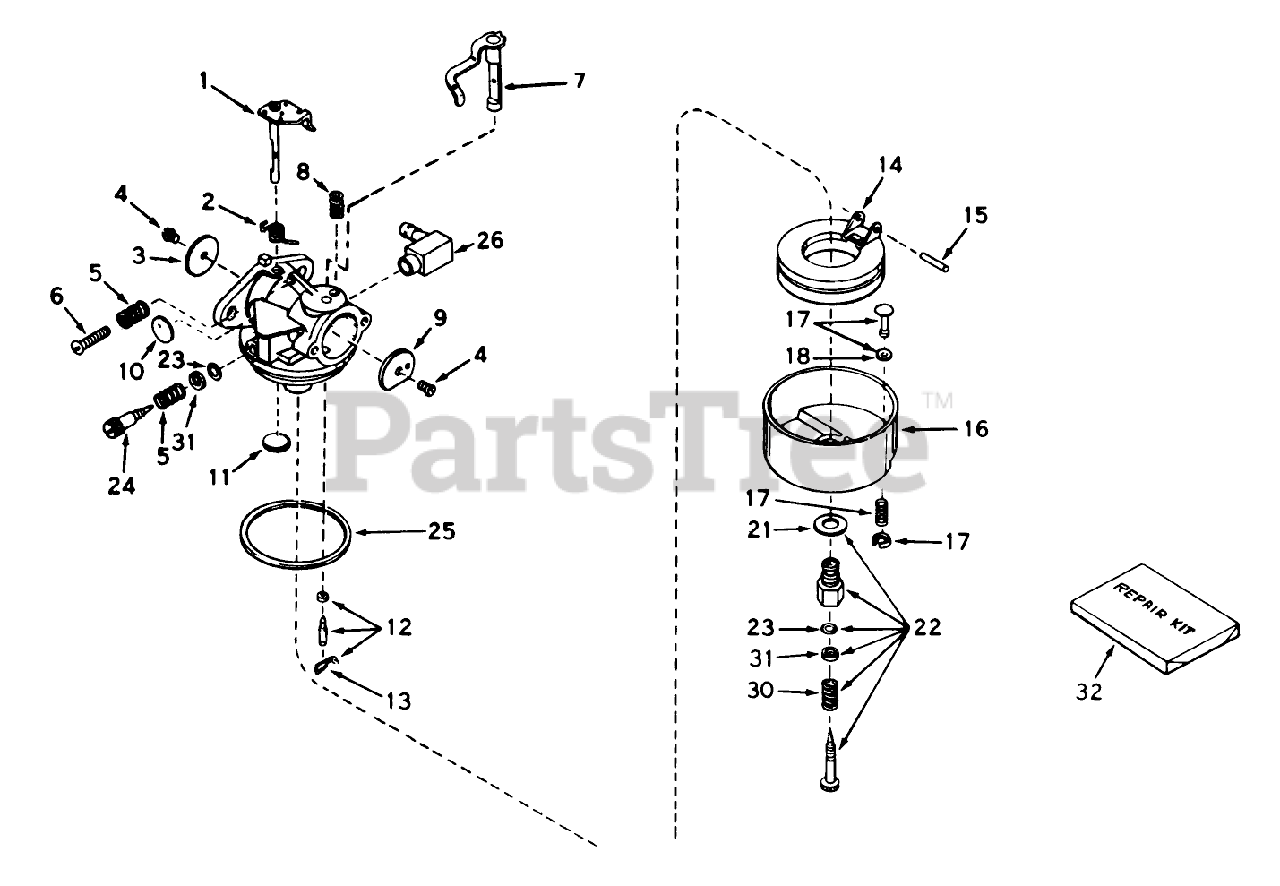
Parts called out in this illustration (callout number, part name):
1	Throttle Shaft and Lever ASM
2	Spring, Throtte Return
3	Shutter-Throttle
4	Screw-Shutter
5	Spring-Tension
6	Screw-Throttle Crack Screw / Idle Speed
7	Shaft/Lever Assy., Choke
8	Spring-Positioning, Choke
10	Plug-Welch, Idle Mixture Well
11	Plug-Welch, Atmospheric Vent
12	Inlet Needle, Seat Clip Assy. (Incl. No. 13)
13	Clip-Spring
14	Float,Carburetor
15	Shaft-Float
16	Bowl-Float (no drain)
17	Bowl Drain ASM
18	Gasket-Plunger, Drain
21	Washer-Bowl Nut
22	Adjustment Screw Assy., Main (Incl. Nos. 5A, 21 23)
23	ORing
24	Screw, Idle Adj.
25	O Ring-Bowl, Float
26	Fitting-Fuel
30	Spring
31	Washer
32	Repair Kit (Incl. items marked *)
